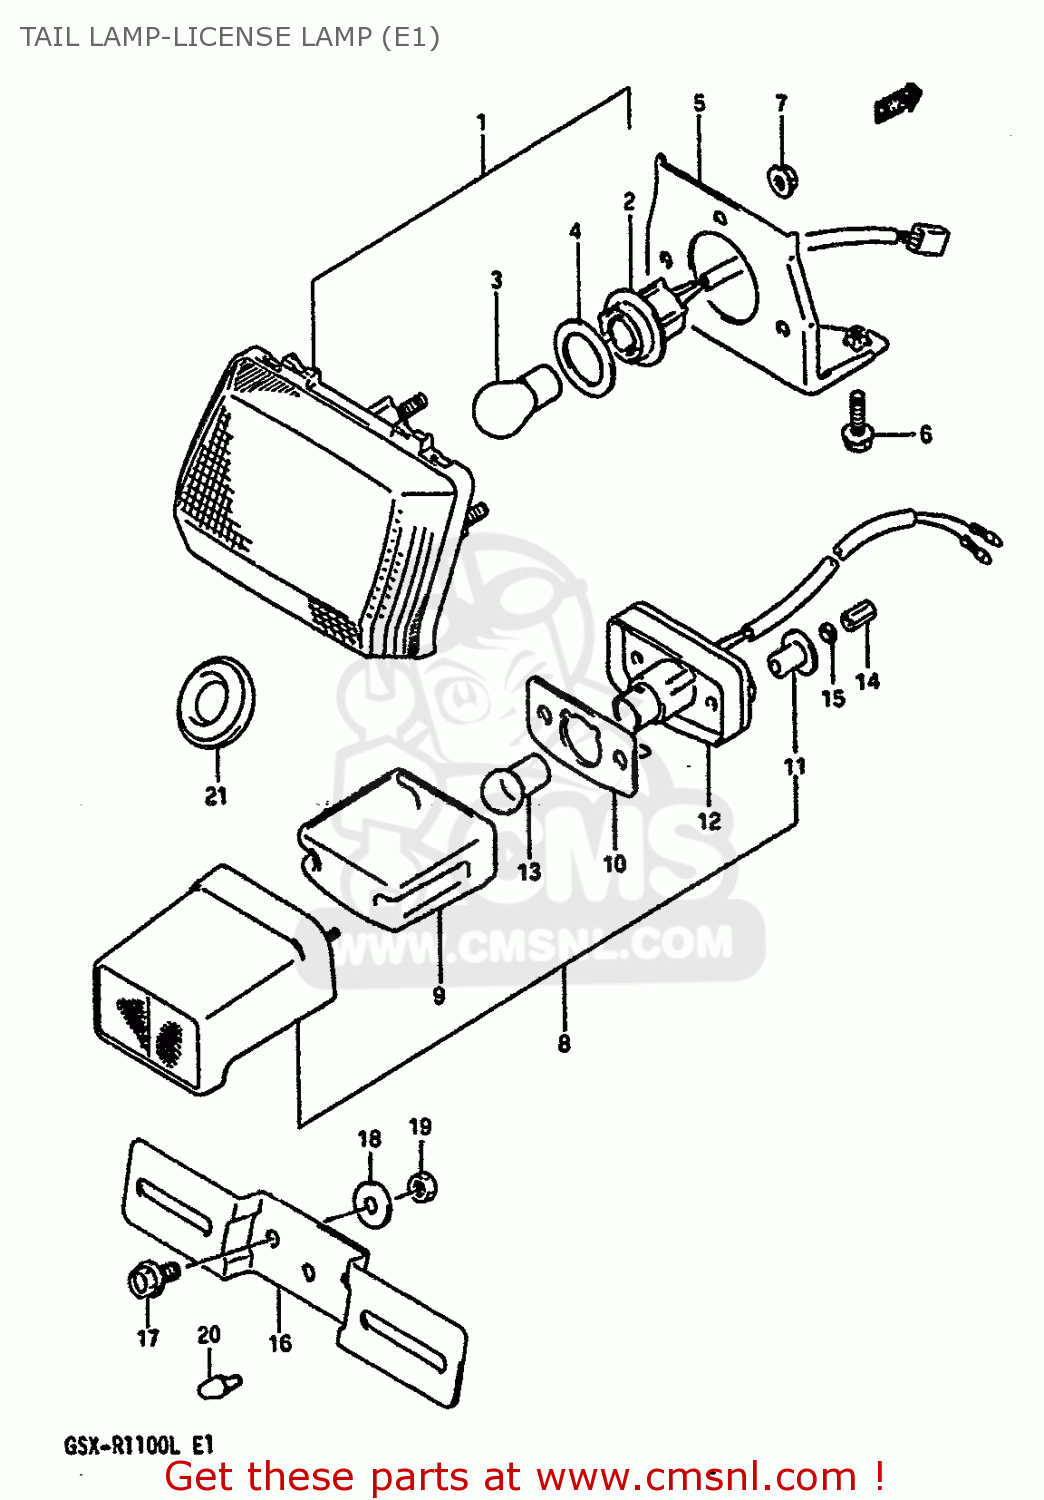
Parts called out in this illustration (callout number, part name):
1	LAMP ASSEMBLY,REAR COMBINATION
2	SOCKET
3	BULB(12V21/5W,BF141-49642A)
4	CUSHION,RUBBER
5	BRACKET COMP,REAR COMBINATION LAMP
6	BOLT
7	NUT
8	LAMP ASSEMBLY,LICENSE
9	LENS
10	GASKET,LICENSE LAMP (NAS)
11	SPACER
12	HOUSING,LICENSE
13	BULB
14	NUT
15	LOCK WASHER
16	BRACKET,LICENSE PLATE
17	BOLT
18	WASHER
19	NUT
20	CUSHION
21	CAP OD:40
